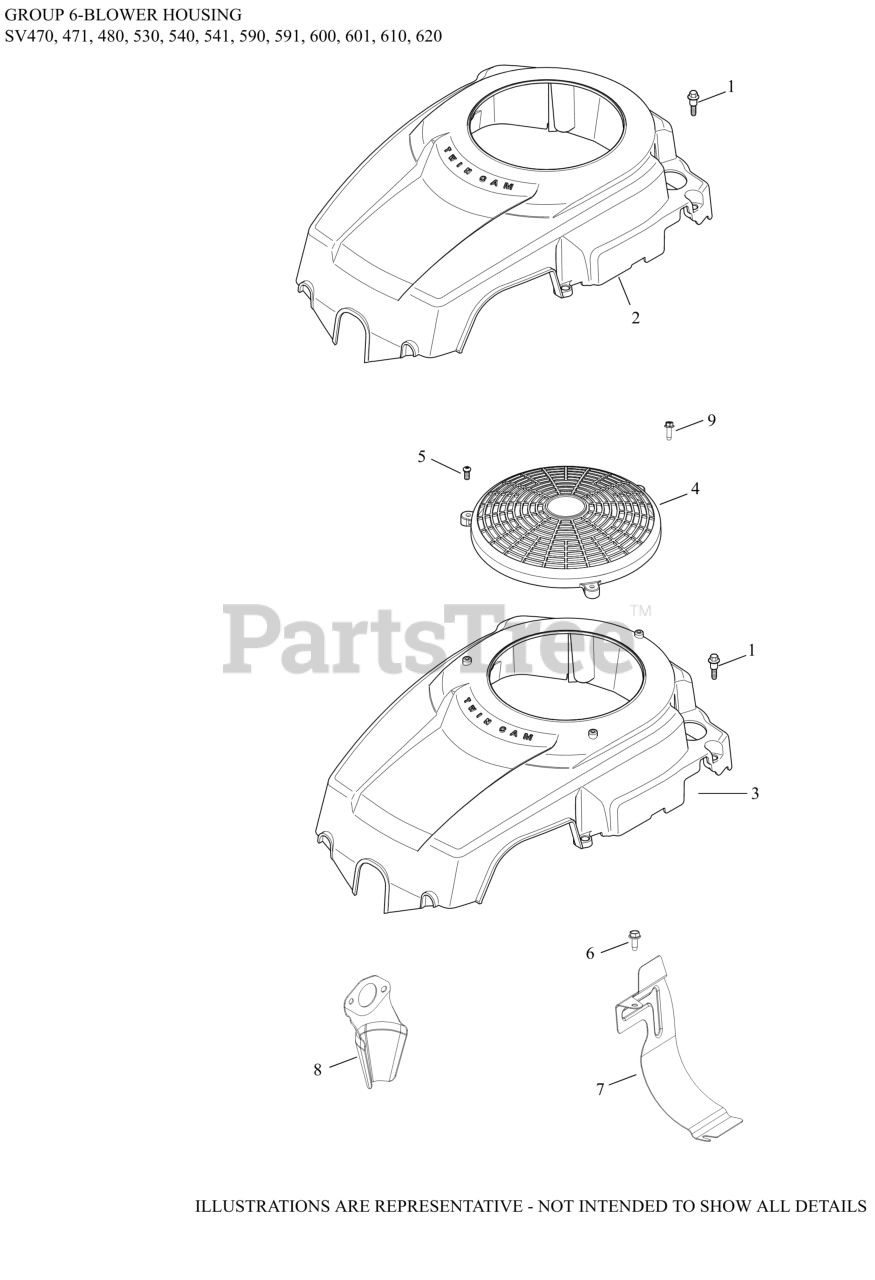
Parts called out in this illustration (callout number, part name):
1	SCREW, SHD THD FRM M6X1X26
2	KIT, BLOWER HOUSING-USE 20 027 13-S
6	SCREW, THREAD FORMING
7	BAFFLE, BARREL-USE 20 063 04-S
9	SCREW, THREAD FORMING
